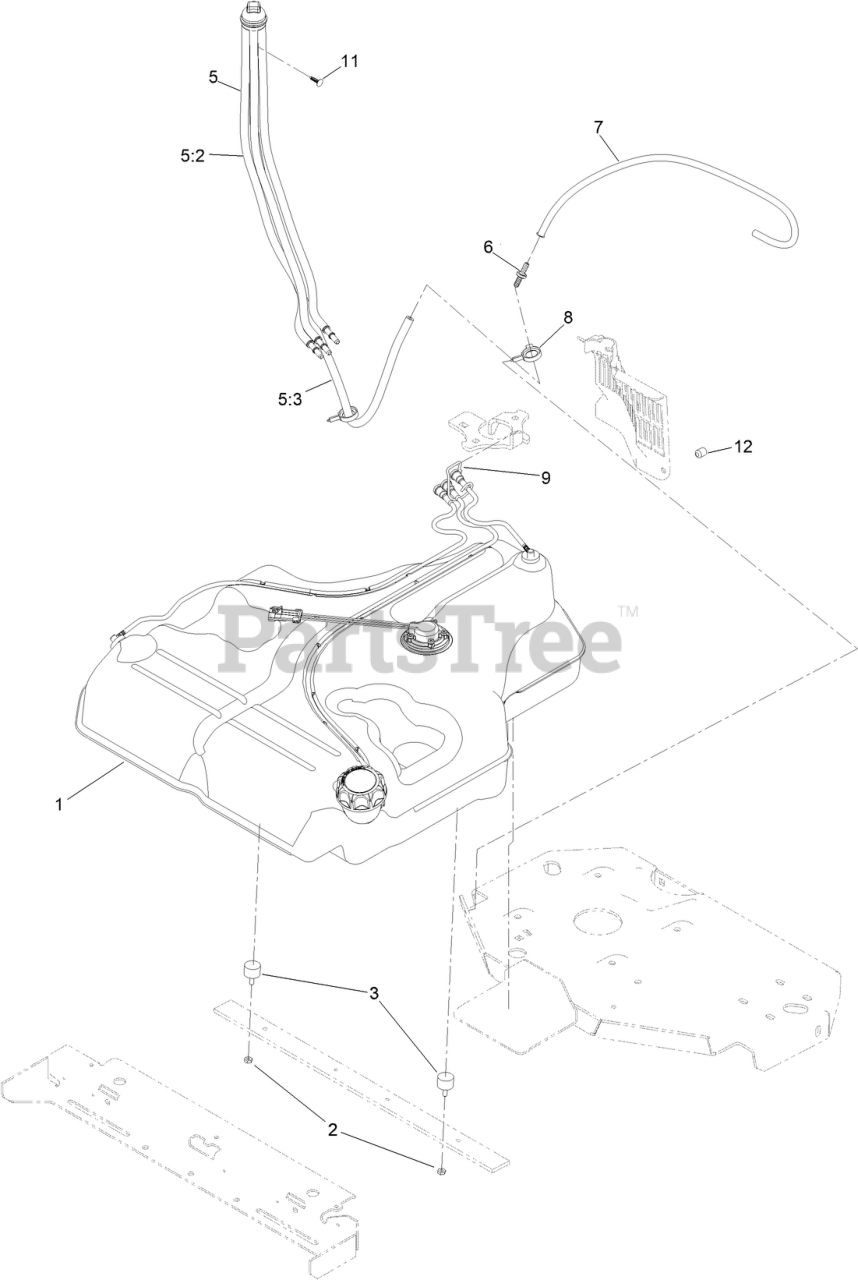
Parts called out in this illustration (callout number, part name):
1	FUEL TANK ASM
2	NUT-JAM
3	BUMPER
5	FUEL MANIFOLD VENT ASM
5:2	HOSE-FUEL
5:3	HOSE-FUEL
6	BARB-FUEL
7	HOSE-FUEL
8	CLAMP-HOSE
9	RETAINER-LINE, VAPOR
11	PLUG-PLASTIC
12	PLUG-PORT
